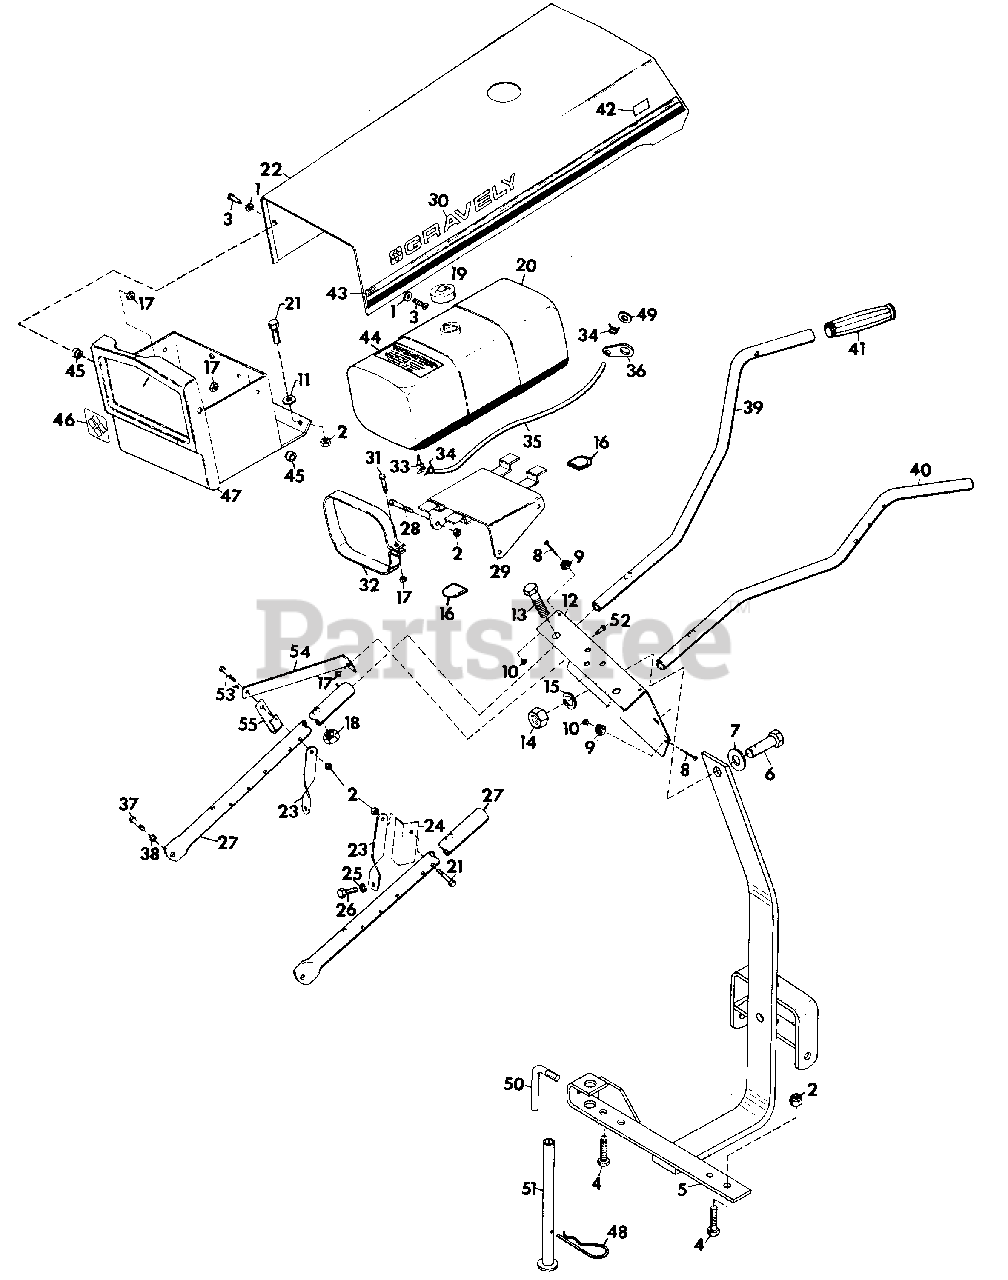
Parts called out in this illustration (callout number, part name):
1	WASHER, FLAT; .281 X .625 X .065
2	NUT, LOCK; 3/8-16 WASHER INSERT HEX
3	SCREW, MACH; 1/4-20 X 1 PAN HD
4	BOLT, HEX; 3/8-16 X 1-1/2
5	HITCH, WELDMENT; 8 H.P.
5	HITCH, WELDMENT; 12 H.P.
6	BOLT, HEX; 5/8-11 X 1-1/2
7	WASHER, FLAT; .656 X 1.250 X .100
8	SCREW, MACH; 6-32 X 5/8 PAN HD C-RECESS
9	BUMPER
10	NUT, MACH LOCK; 6-32 WASHER INSERT
11	WASHER, FLAT; .406 X .812 X .065
12	INSTRUMENT PANEL ELECTRIC START
12	INSTRUMENT PANEL MANUAL START
13	BOLT, HEX; 1/2-20 X 2
14	NUT, HEX; 5/8-11
15	WASHER, LOCK; 5/8 SP
16	COVER 1.0 X .125 X 1.0
17	NUT, LOCK; 1/4-20 WASHER INSERT
18	NUT, HEX; 1/2-20
19	CAP, GAS TANK
20	ASSEMBLY, FUEL TANK
21	BOLT, HEX; 3/8-16 X 2-1/4
22	HOOD
23	BRACE, HANDLE
24	STOP, ROD
25	WASHER, LOCK; 7/16 SP HEAVY
26	BOLT, HEX; 7/16 X 1-1/2
27	SUPPORT, TUBE
28	BOLT, HEX; 3/8-16 X 1-7/8
29	WELDMENT, FUEL TANK BRACKET
30	DECAL, GRAVELY LOGO
31	BOLT, HEX; 1/4-20 X 1-1/4
32	STRAP, FUEL TANK
33	VALVE AND STRAINER
34	CLAMP, FUEL HOSE
35	LINE, FUEL .50 OD X .25 ID X BULK LENGTH
36	BRACKET, FUEL LINE
37	BOLT, HEX; 3/8-16 X 1
38	WASHER, LOCK; 3/8 SP
39	BAR, RIGHT HANDLE
40	BAR, LEFT HANDLE
41	GRIP, HAND
42	DECAL, MODEL 5665
42	DECAL, MODEL 5260
42	DECAL, MODEL 5645
43	DECAL, SIDE STRIPES
44	DECAL, ELECTRICAL SYSTEM WARNING
45	PIVOT, HOOD
46	DECAL
47	WELDMENT, GRILLE
48	COTTER, HAIR PIN
49	WASHER, FLAT; .469 X .938 X .065
50	HANDLE, ADJUSTING
51	KICK STAND
52	BOLT, HEX; 1/4-20 X .625
53	BOLT, HEX; 3/8-16 X 2-1/2
54	BRACE, INSTRUMENT PANEL
55	RETAINER, 2-SPEED CONTROL
